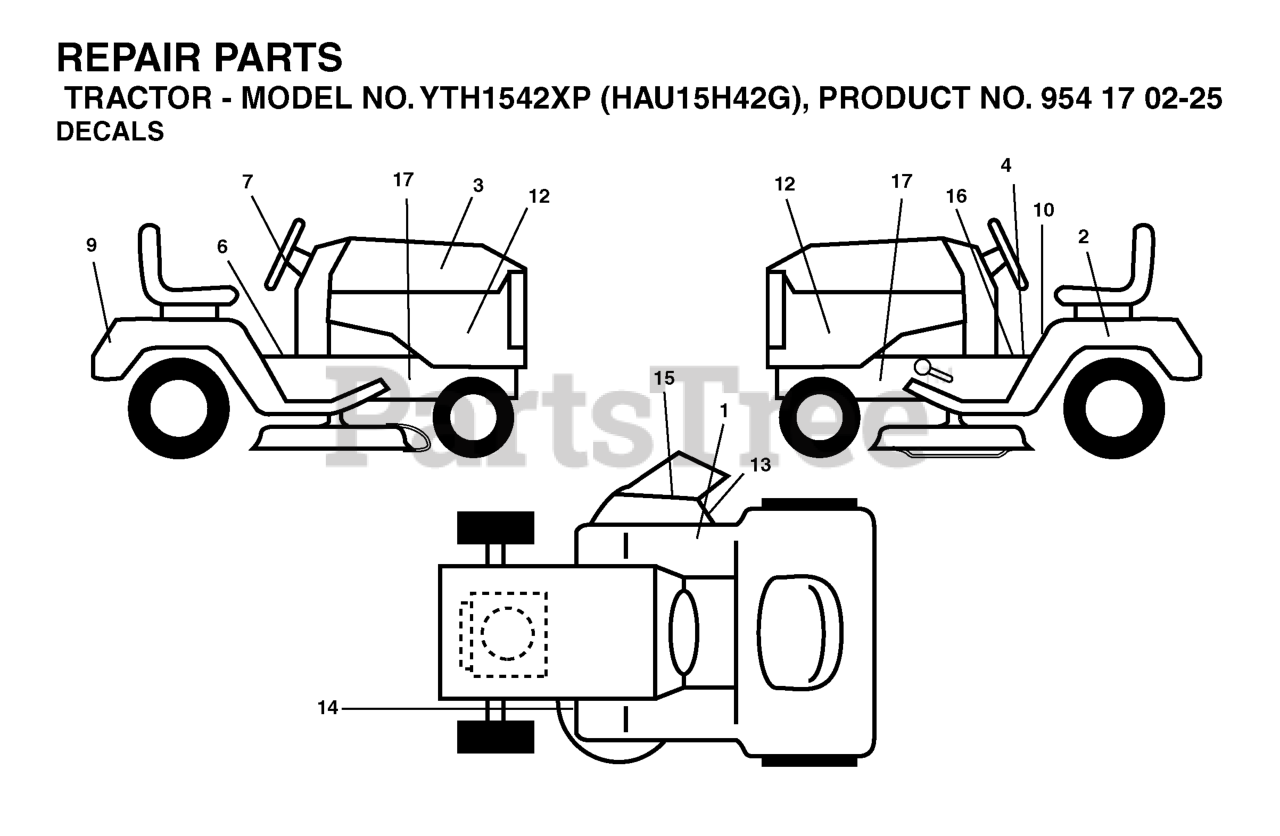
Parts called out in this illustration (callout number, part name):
1	DECAL
2	DECAL BTRY SYMBOLS
3	DECAL.HOOD.HUSQVARNA.INTERNATI
4	DECAL
6	DECAL PARK BRAKE
7	DECAL.STEERING.HUSQ.BLUE
10	DECAL READ OWNER'S MAN SYMS
13	DECAL.INTERNATIONL.CUTFINGER
14	DECAL V BELT SCHEMATIC
15	DECAL DECK "B" 42"
16	DECAL
